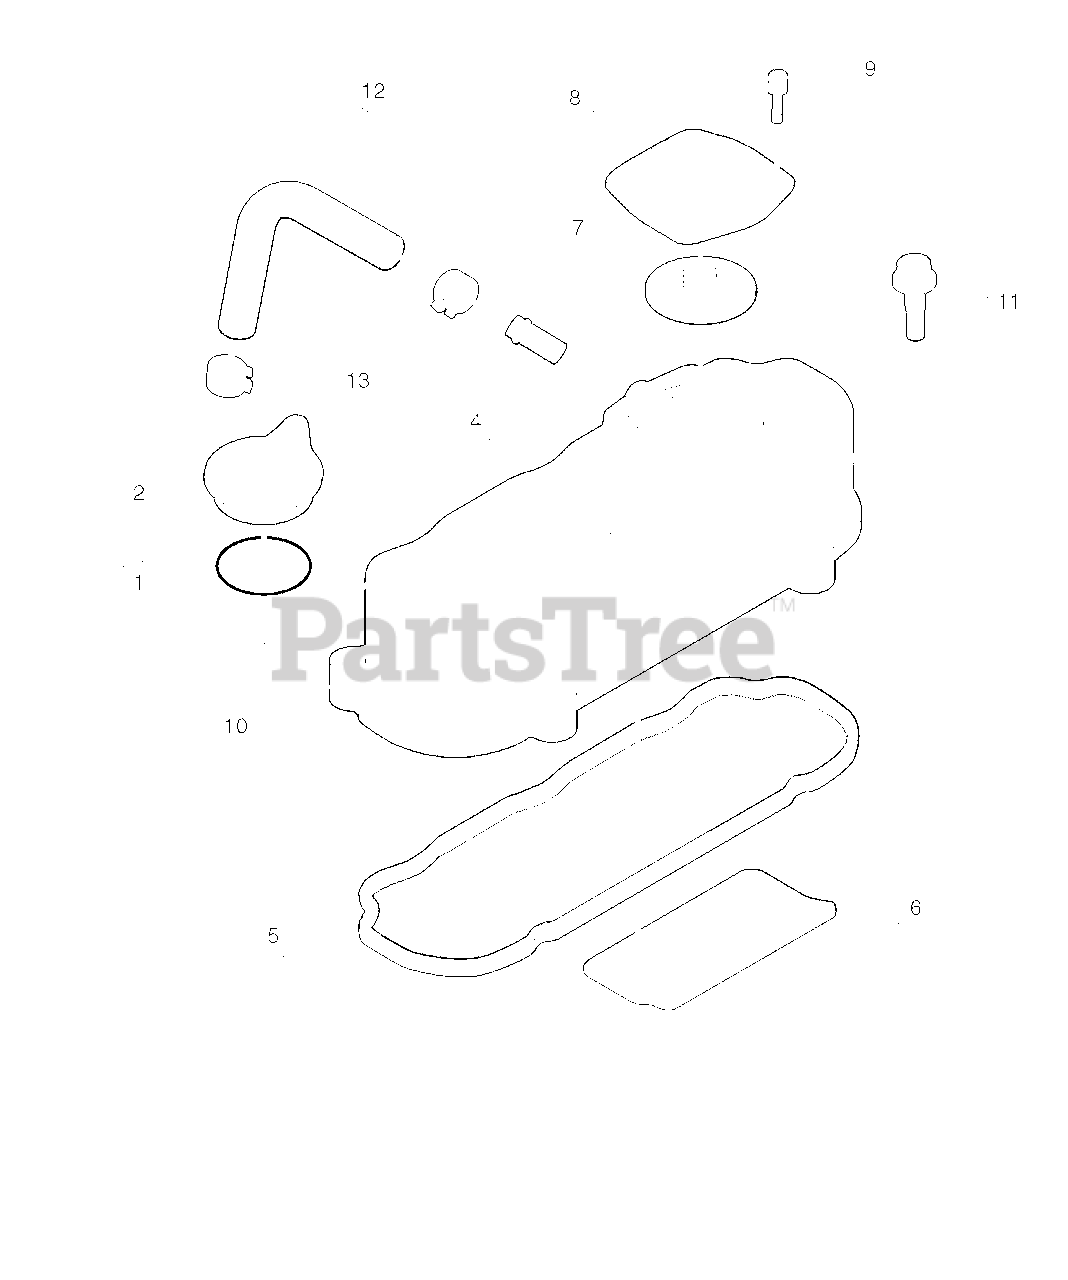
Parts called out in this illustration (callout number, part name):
1	O Ring, 30 X 36
2	Plug, Oil Filler
3	Assembly, Cylinder Head Cover
4	Pipe, Water Return, D722
5	Gasket, Cylinder Head Cover
6	Shield, Breather
7	Valve, Breather
8	Cover, Breather
9	Screw, Breather
10	Cover, Cylinder Head
11	Bolt, Cylinder Head Cover
12	Tube, Breather
13	Clamp, Breather Tube
